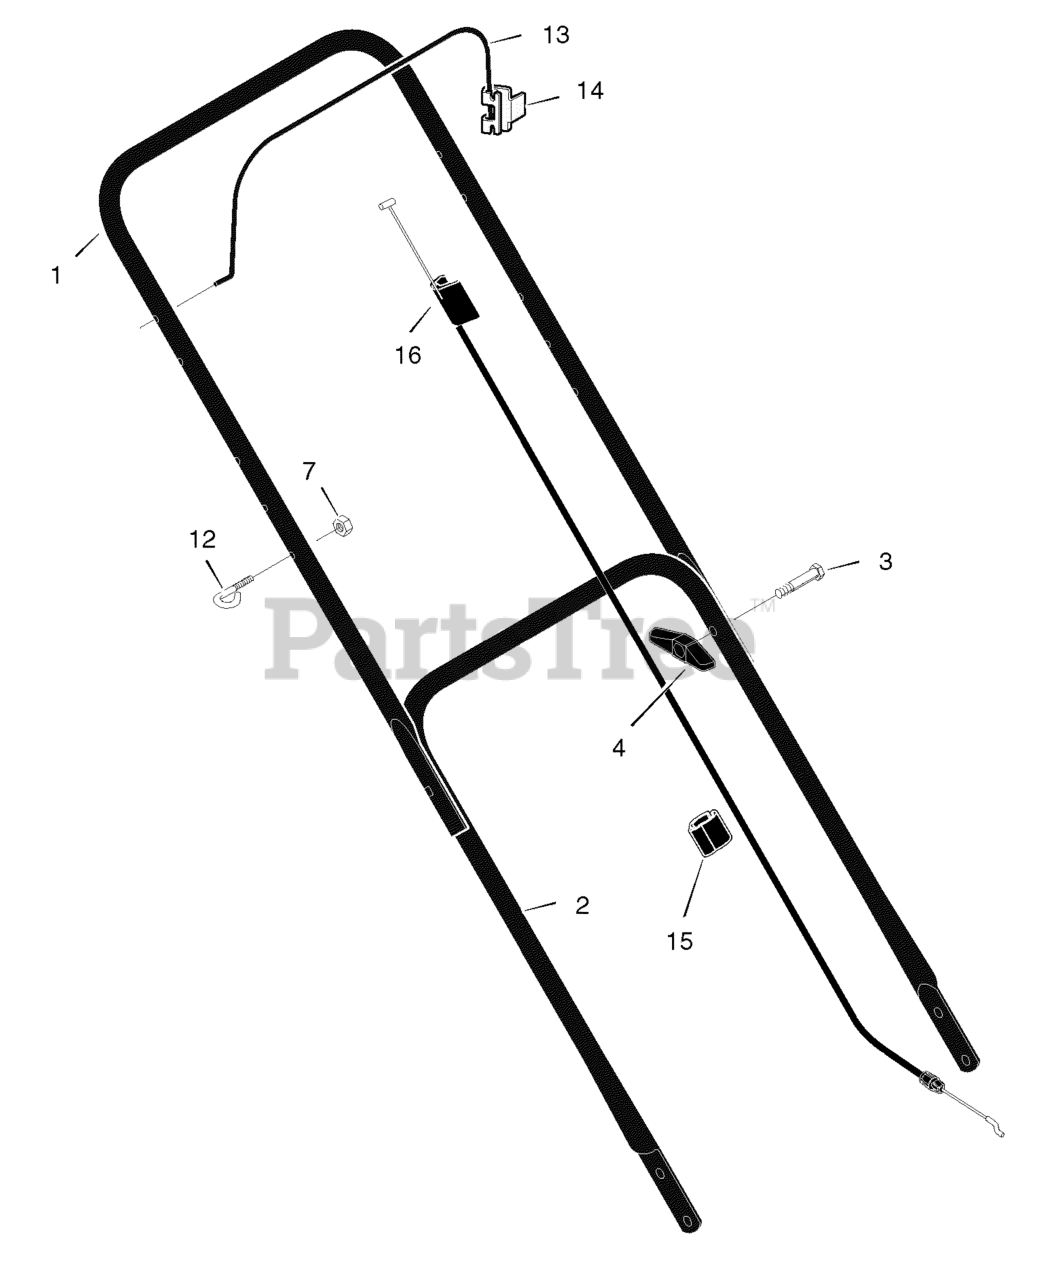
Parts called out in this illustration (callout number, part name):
1	Handle, Upper (Black)
2	Handle, Lower (Black)
4	Knob, Plastic
7	Locknut
12	Guide, Rope
13	Engine Stop Lever
14	Bracket, Stop Lever
15	Clamp, Cable
16	Engine Stop Cable *
